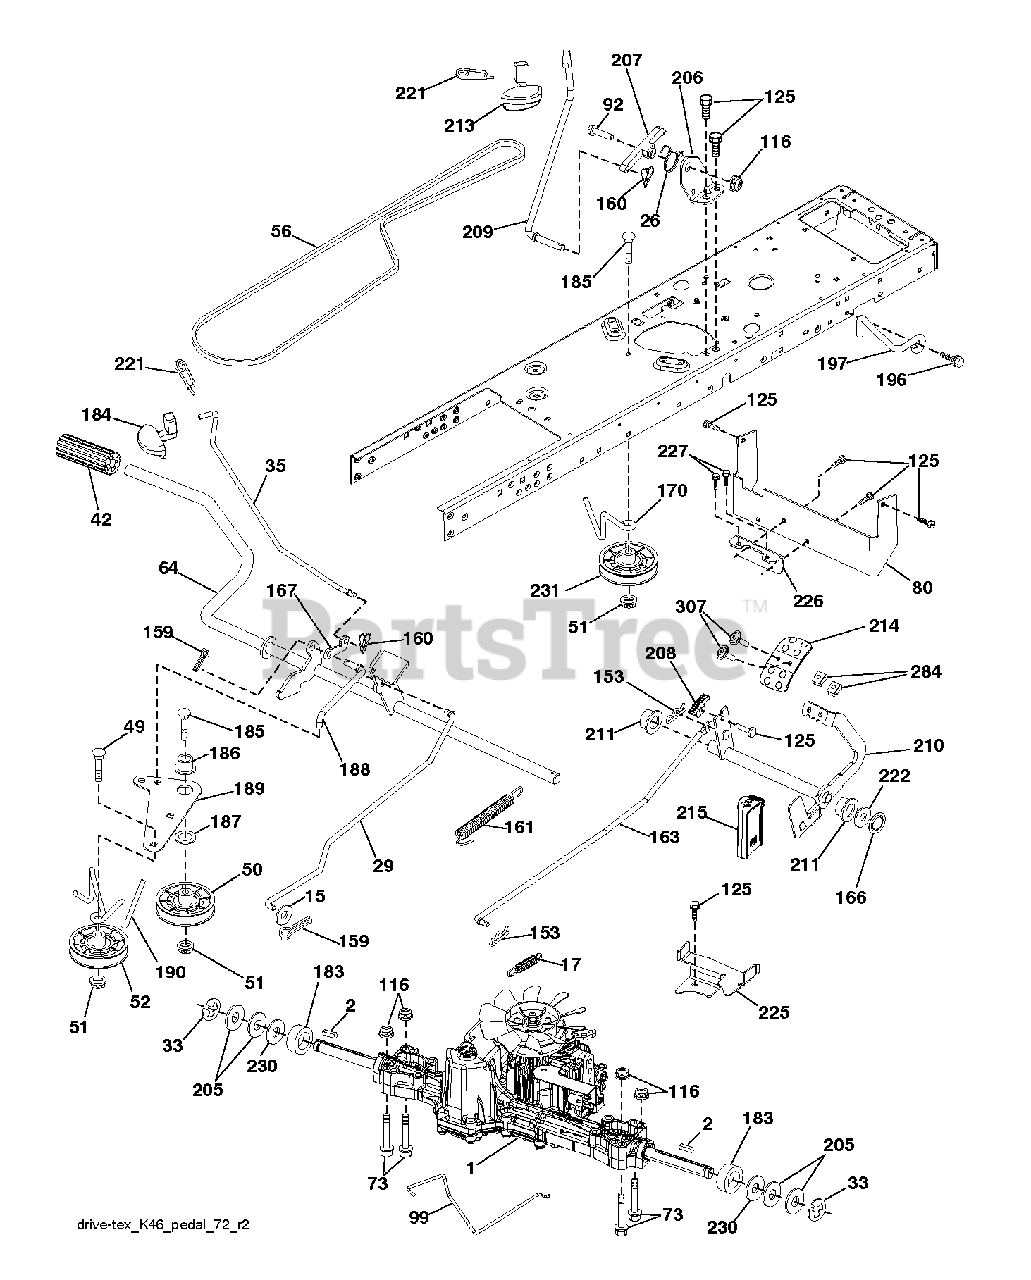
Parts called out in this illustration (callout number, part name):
2	SQUARE KEY
15	WASHER
17	SPRING.BRAKE.K46.GREEN
26	SPRING.RETURN.CRUISE
29	ROD.BRAKE.K46
35	ROD.BRAKE.PARTK.HUSQ.TEX
42	PEDAL COVER T
50	IDLER.FLAT.910.OFFSET
51	NUT LOCK FLG 3/8-16 UNC
52	IDLER.V-GROOVE.910.OFFSET
56	V-BELT.MOWER.92.40.42/K46
64	SHAFT.ASM.PEDAL.BRK.CNTR
80	STRAP.TORQUE.K46.K57R.TT
92	BOLT
99	ROD.SPRING.BYPASS.K46.LT.Z
116	NUT LOCK HEX FLANGE 5/16-18
125	SCREW
153	RETAINER M
159	COTTER PIN
160	RETAINER CLIP
161	SPRING, RETURN LT
163	ROD.CONTROL.PEDAL.K46
166	NUT.PUSH.625
167	LATCH.BRAKE.SPRING
170	KEEPER.CENTER SPAN.1.688
183	SPACER AXLE
184	RB HANDLE.PARKG.BRK.HUS/PRED
186	SPACER.RETAINER
187	WASHER 12/32X2X10GA
188	RP LINK.CLUTCH.GROUND.DRIVE
189	BELLCRANK.GROUND.DRIVE.TEX.
190	KEEPER.BELLCRANK.DRIVE
196	SCREW 3/8-16X1
197	LINK.CLUTCH.ANIT-ROTAT
206	BRKT.MOUNT.LATCH.CRUIS
207	LATCH.CONTROL.CRUISE
208	GEAR.SECTOR.CONTROL.CR
209	ROD.CONTROL.CRUISE.GT.
210	ROCKER.ASM.PEDAL.CONTR
211	BEARING.NYLON
213	KNOB.CONTROL.CRUSIE.HU
214	PEDAL.FORWARD.HUSQVARNA.DEALER
215	PEDAL.REVERSE.TEX.GT.4
221	RETAINER.SPRING.CLIP.H
222	WASHER 21/32 X 1-1/4 X 10 GA.
225	KEEPER.BELT.TRANSAXLE.K46
226	BRACKET.MOUNT.TORQUE.K46.TLT
227	SCREW
230	WASHER.HARDENED
231	IDLER.V-GROOVE.1.688.OFFSET
284	NUT.U-CHNL.1/4-20.550DP.350PNL
307	SCREW.MACHINE.CR.1/4-20
